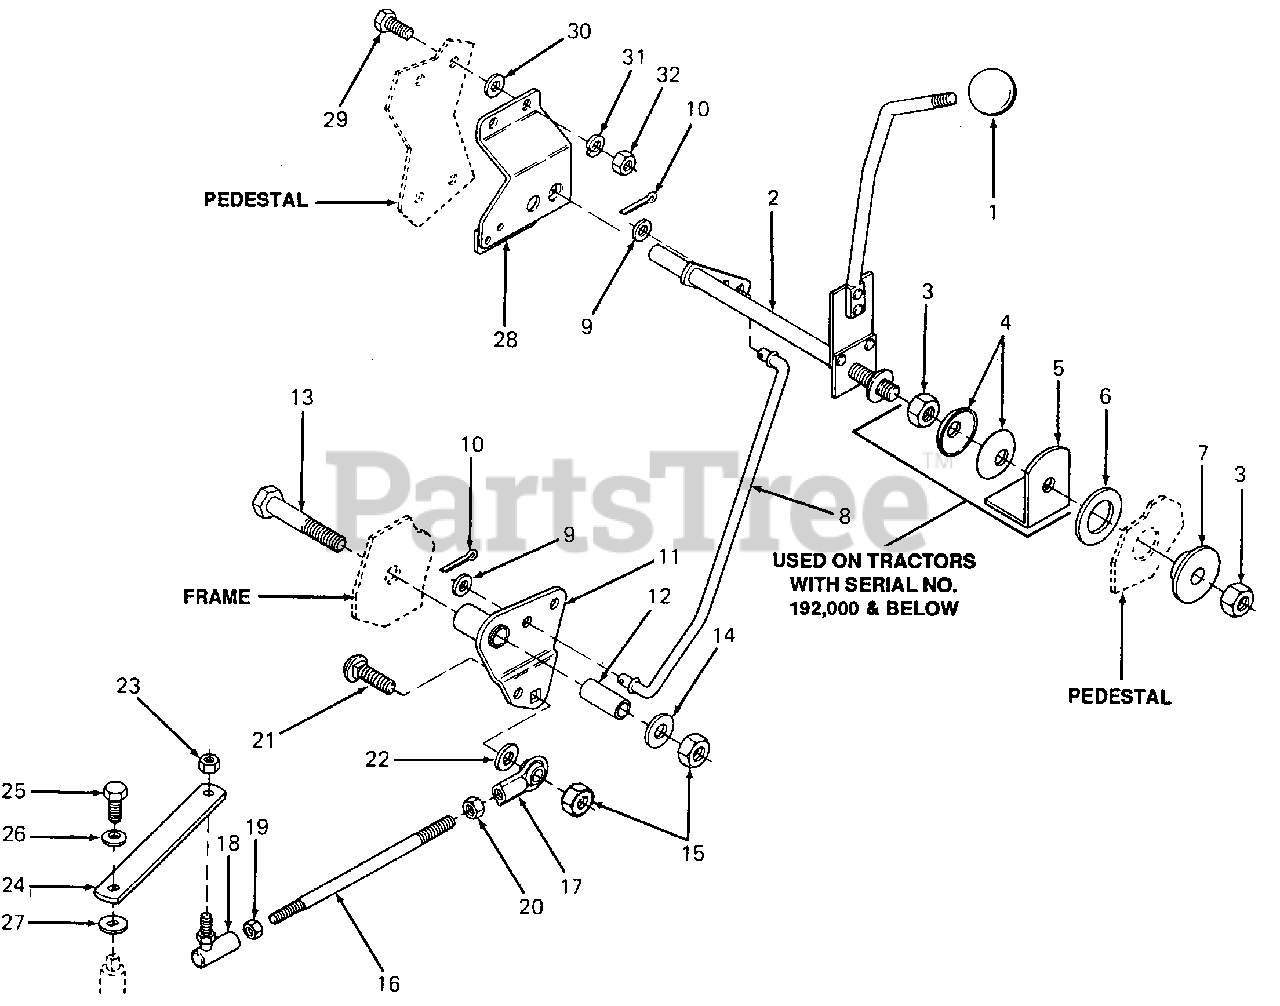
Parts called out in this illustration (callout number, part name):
1	Knob, Control
2	Shifter Assy
3	Nut, Hex Top Lock, 1/2-20
4	Washer, Bell
5	Bracket, Friction
6	Washer, Friction
7	Spacer, Shoulder
8	Rod, Upper Shift
9	Washer, Flat, .406 X .75 X.063 Thk
10	Pin, Cotter, 1/8 X 1.0 Lg
11	Cam, Shift
12	Sleeve, .380 X .623 X 1.555 Lg
13	Screw, Hex Cap, 3/8-16 X 2.25 Lg GR5
14	Washer, Flat, .385 X .87 X 0.6 Thk HDN
15	Nut, Hex Center Lock, 3/8-16
16	Rod, Shifter
17	Joint, Ball
18	Joint, Ball - LH Trd
19	Nut, Hex Jam, 5/16-24 LH Trd GR5
20	Nut, Hex Jam, 3/8-24 GR5
21	Bolt, Sht Nk Carr, 3/8-16 X 1.0 Lg GR5
22	Washer, Flat, .385 X .62 X .063
23	Nut, Hex Patch Lock, 5/16-24
24	Lever, Shifter
25	Screw, Hex Patch Lock, 1/4-28 X .62 Lg GR5
26	Washer, Bell
28	Bracket, Clutch Handle
29	Screw, Hex Cap, 1/4-20 X .62 Lg GR5
30	Washer, Flat, .281 X .75 X .105
31	Washer, Lock, 1/4
32	Nut, Hex, 1/4-20 GR5
